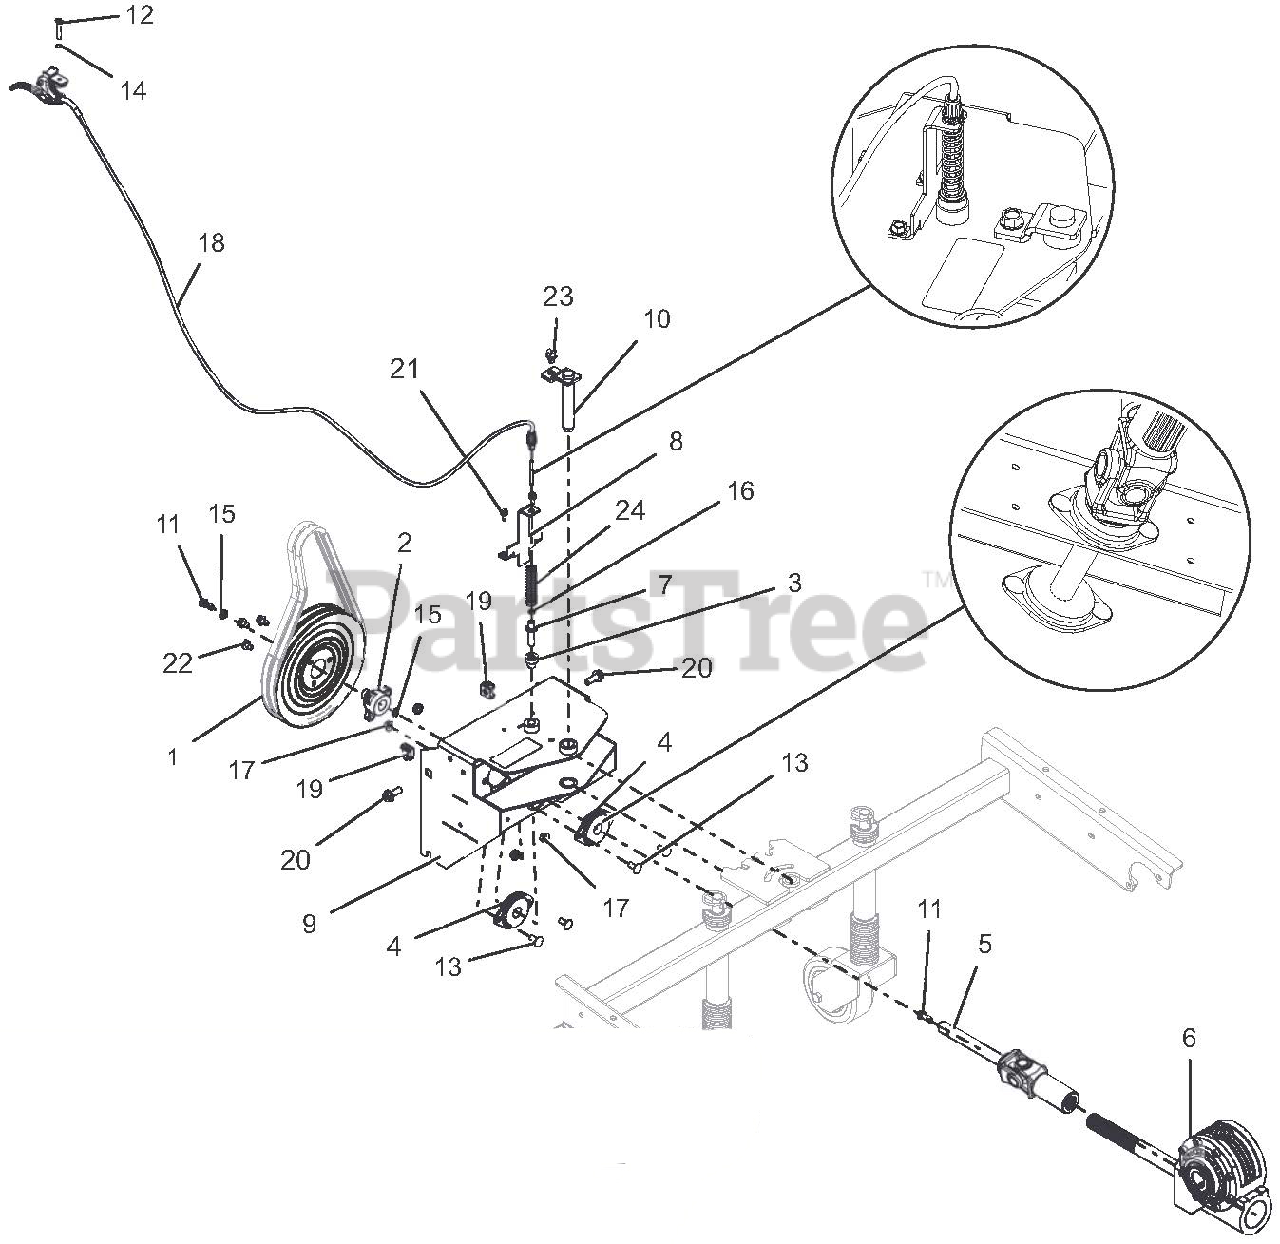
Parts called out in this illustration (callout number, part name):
1	PULLEY, SPIN FORM DUAL GROOVE
2	PULLEY HUB, BOLT-ON D-BORE .75
3	SPACER -FLANGED .390X.500X.781
4	BEARING, 2 BOLT FLANGE -.75 ID
5	DRIVELINE, SERIES 07 (U-JOINT)
6	GEARBOX, WORM - 8.25:1
7	PIN, ADJUSTABLE ANGLE BRUSH
8	BRKT, PIN HOLDER
9	ADAPTER, BRUSH
10	WLDMT, BRUSH PIN
11	BLT-HEX .31-24X.75 YWZC GR5
12	SCR-MCH .25-20X1.50 OVAL HD
13	@BLT-RDHDSQNK .31-18X.75 G5YZ
14	WSHR-LK-INT .250 TH TYA
15	WSHR-LK .312X.097 HVY YWZC
16	@NUT-HEX 10-24 YWZC
17	@NUT-LK-TOP-FLG .31-18 YWZC
18	CABLE, REMOTE BRUSH LOCK
19	NUT-RETNR .38-16 TINRMAN
20	BLT-SERHFWH .375-16X1.0 YWZC
21	SCR-TAP .25-20X.50 HWH TR YWZ
22	@SCR-TAP .31-18X.50 HWH TR YWZ
23	@SCR-TAP .38-16X.50 HWH TR YWZ
24	SPRING, COMPRESSION
